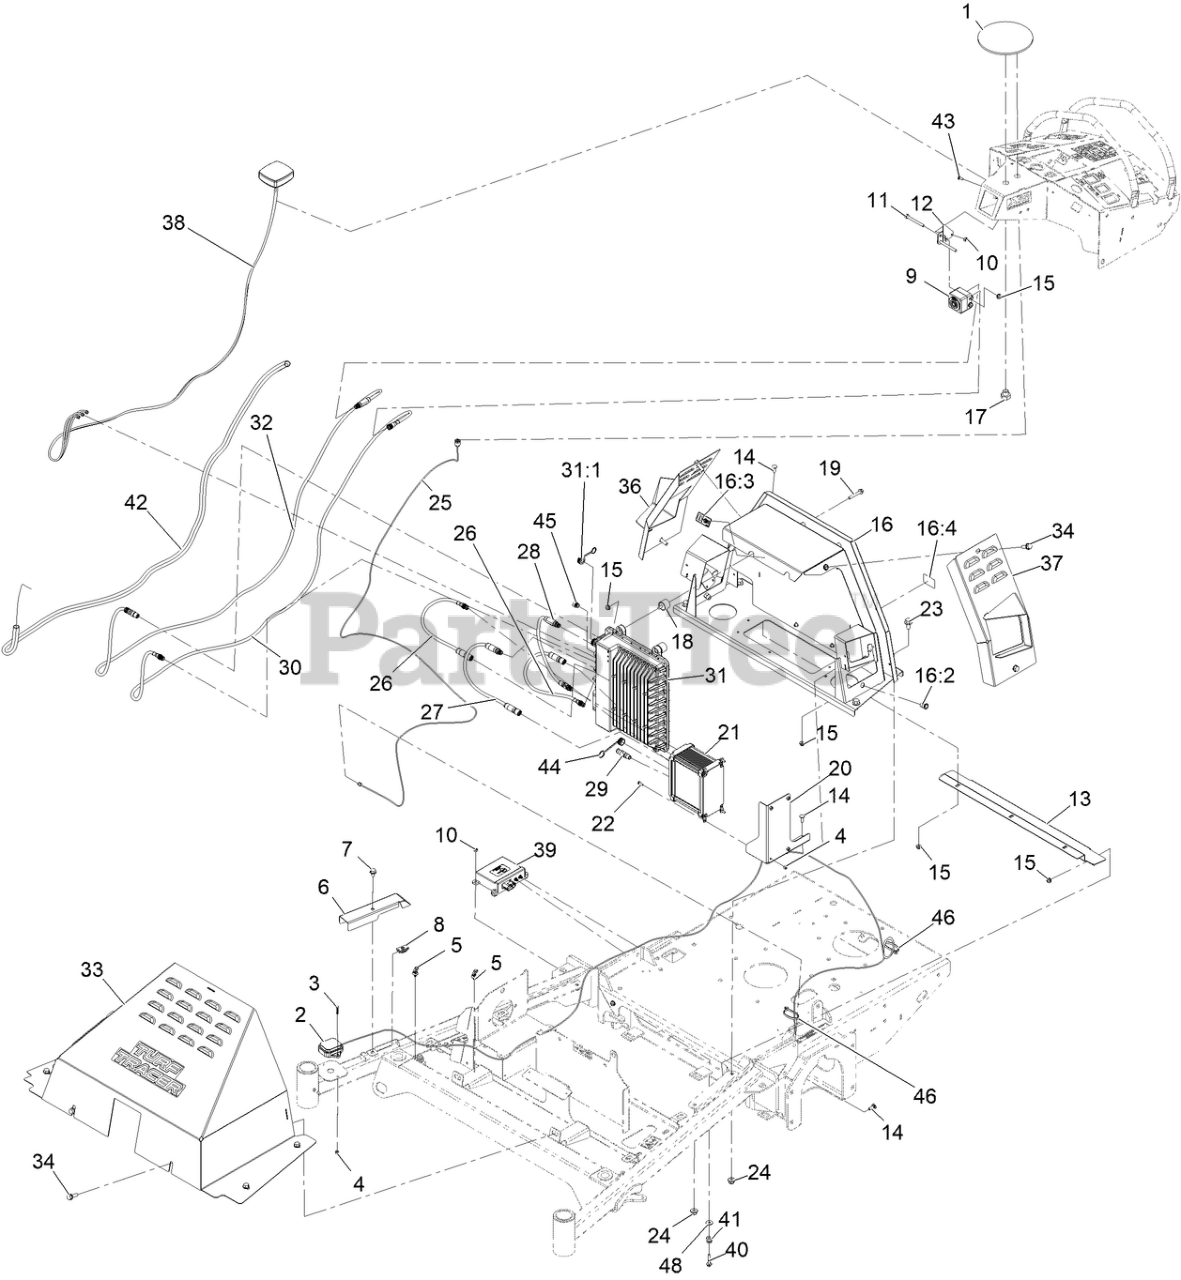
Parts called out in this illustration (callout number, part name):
1	ANTENNA-GPS
2	ANTENNA-GPS
4	NUT-LOCK
5	CLIP-TIE, FIR TREE W/TIE, 5MM/.196"" HOLE
6	COVER-WIRE
7	SCREW-HHF
8	Nut-Retainer
9	CAMERA - 180 DEGREE FOV
10	NUT-LOCK, NI
11	SCREW-HH
12	BRACKET-CAMERA
13	SHIELD-HEAT, LOWER
14	BOLT-CARR
16	Acs Mount ASM
16:2	Nut-Clinch
16:3	DECAL-NO SPRAY
16:4	DECAL-WARNING
17	SCREW-HH,
18	MOUNT-CYLINDRICAL
19	Screw-HHF
20	BRACKET-CONTROLLER
21	Controller - Radar
22	SCREW-HHF, SERRATED
23	Screw-HH Flg 3/8-16 X 3/4
24	NUT-HF, NI
25	GPS ANTENNA CABLE
26	CABLE - RADAR IO M/F
27	CABLE -RADAR PWR
28	CABLE - RADAR ETHERNET
29	CABLE ASSY, ACS NOVA 2.1, RADAR PLUG
30	CABLE - CAMERA PWR
31	Controller-Autonomous
31:1	COVER - M12
32	CABLE - CAMERA IO
33	Hood ASM
34	SCREW-HHF
36	WELD-PANEL ACCESS, RH
37	WELD-PANEL ACCESS, LH
38	ANTENNA - CELL/WIFI
39	KIT-INS
40	SCREW-SHOULDER
41	ISOLATOR-RUBBER
42	LOOM-SPLIT
43	BOLT-CARR
44	COVER - M16
45	PLUG - LIDAR
46	TIE-CABLE
48	WASHER-FLAT
